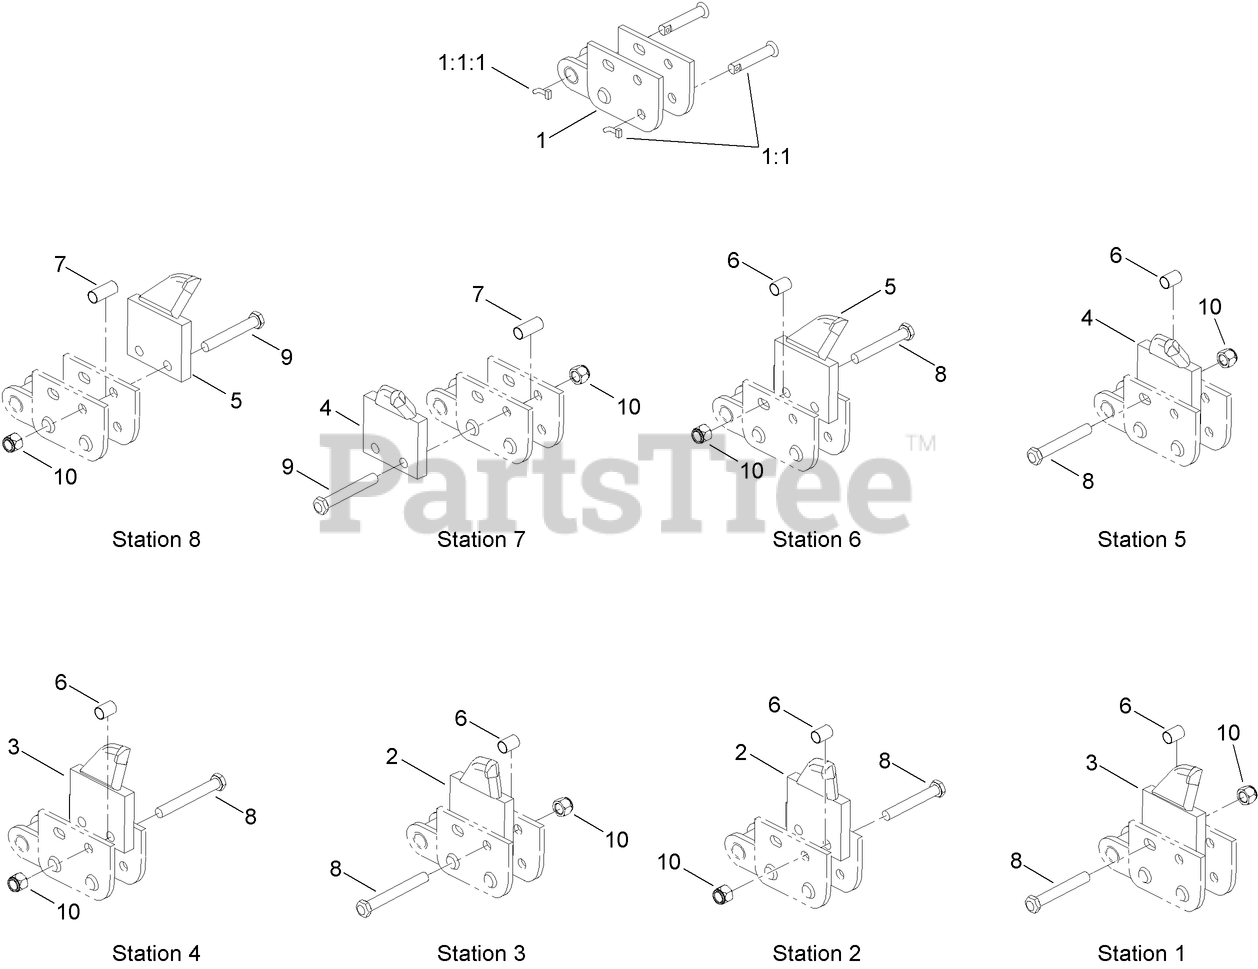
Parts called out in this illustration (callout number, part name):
1	CHAIN REPAIR LINK ASM
1:1	NOTCHED PIN AND KEEPER ASM
1:1:1	PIN-KEEPER
2	TOOTH-TERMINATOR, RH CENTER
3	TOOTH-TERMINATOR, LH CENTER
4	TOOTH-TERMINATOR, RH
5	TOOTH-TERMINATOR, LH
6	SPACER-TUBE, INSIDE ADAPTER
7	SPACER-TUBE, OUTSIDE MOUNT
8	BOLT-HH
9	BOLT-HH
10	NUT-LOCK
